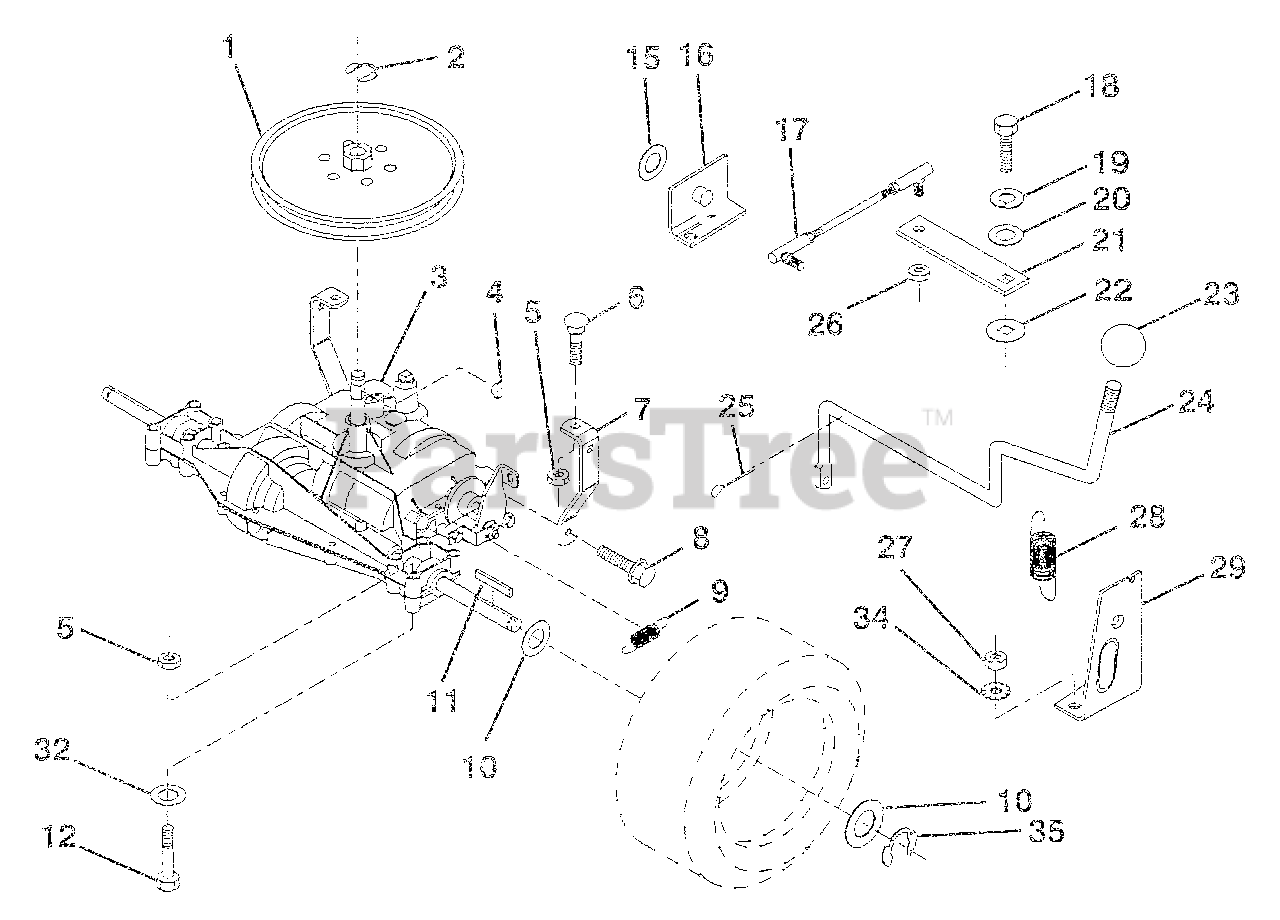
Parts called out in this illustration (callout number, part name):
2	Ring, Retainer
4	Key, Woodruff #9
5	Nut, Crownlock 5/16-18
6	Bolt, Carriage 5/16-18 UNC x 3/4
7	Strap, Torque
8	Screw 5/16-18 x 3/4
9	Spring, Brake
10	Washer 25/32 x 1-1/4 x 16 Ga.
11	Key, Square
12	Bolt, Fin Hex 5/16-18 x 2-1/2
15	Washer 17/32 x 1 x 16 Ga.
16	Support Handle Shift LH
17	Link, Shift
18	Bolt, Fin Hex 1 /4-28 UNF x 3/4 Gr. 8
19	Washer, Lock 1/4
20	Washer 9/32 x 3/4 x 10 Ga.
21	Arm, Shift
22	Washer, Shift Plate
23	Knob, Fed 1/2-13
24	Handle, Asm. Shift
25	Pin, Cotter 1/8 x 1
26	Locknut 5/16-24 UNF
27	Nut, Keps 5/16-18
28	Extension, Spring
29	Support Handle Shift RH
32	Washer 11/32 x 11/16 x 16 Ga.
34	Washer External Tooth 5/16
